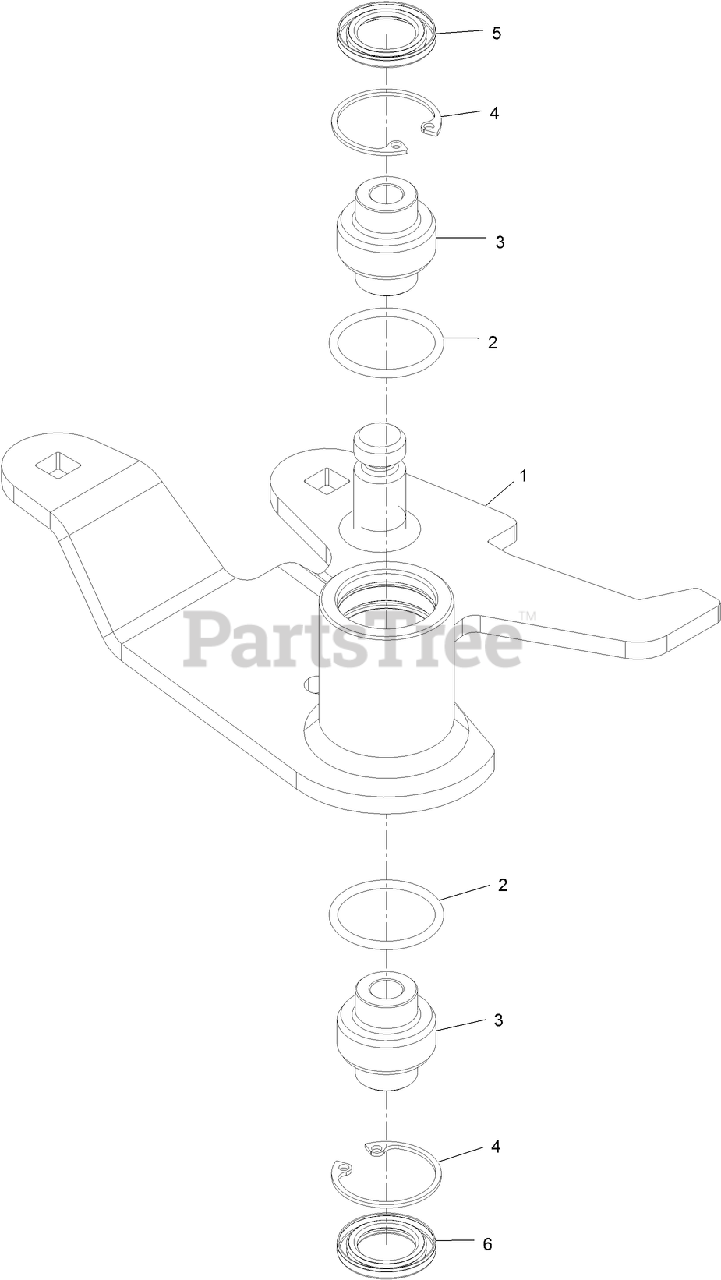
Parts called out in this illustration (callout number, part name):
1	ASM-IDLER ARM, 96RD [RED]
2	O-RING
3	BEARING-SPHERICAL
4	RING-SNAP
5	SEAL-LIP, SINGLE
6	SEAL-LIP, DOUBLE
